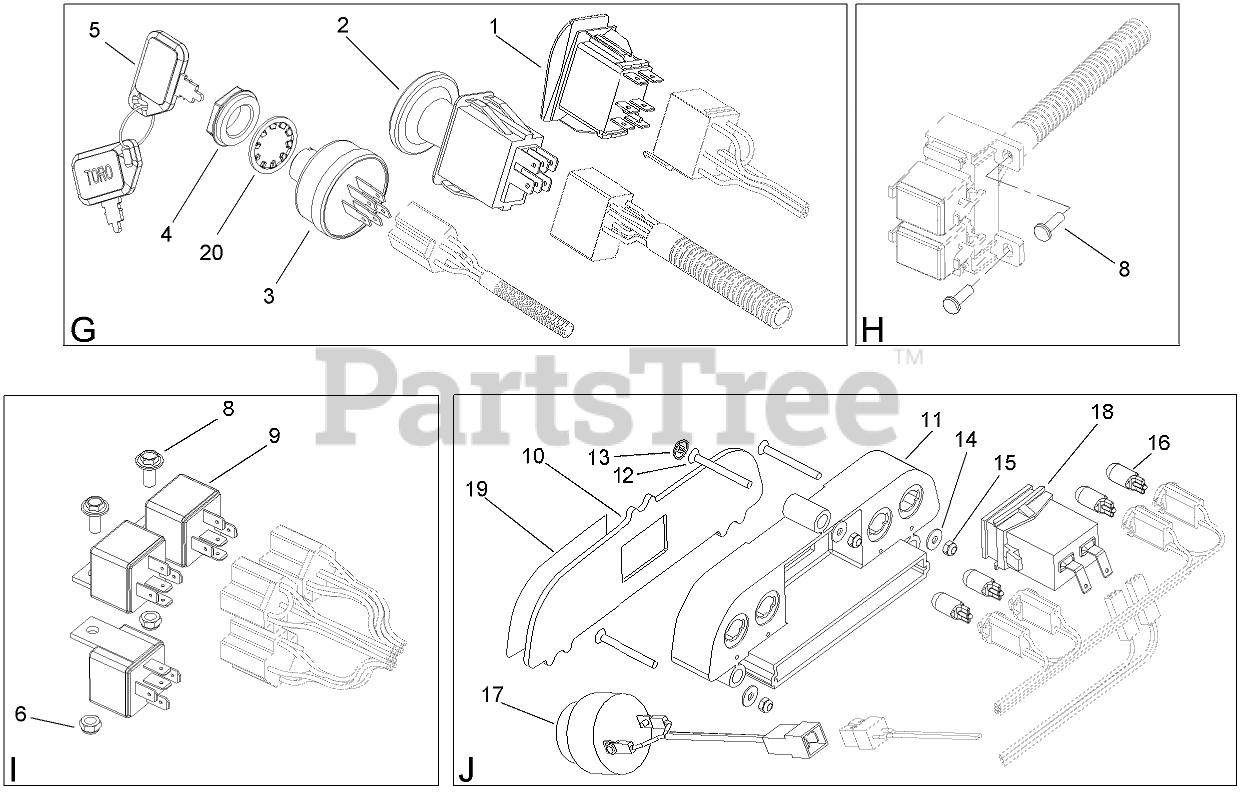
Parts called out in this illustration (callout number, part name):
1	SWITCH-CRUISE
2	SWITCH-PTO
3	SWITCH-IGNITION
4	NUT-HH
5	KEY-IGNITION
6	NUT-LOCK
8	SCREW-HEX
10	LENS-DASH
11	HOUSING-LIGHT, INDICATOR
13	CAP-SCREW
14	WASHER
15	NUT-HEX
17	BUZZER
18	HOURMETER
19	DECAL-DASH
20	WASHER-TOOTH, INTERNAL
